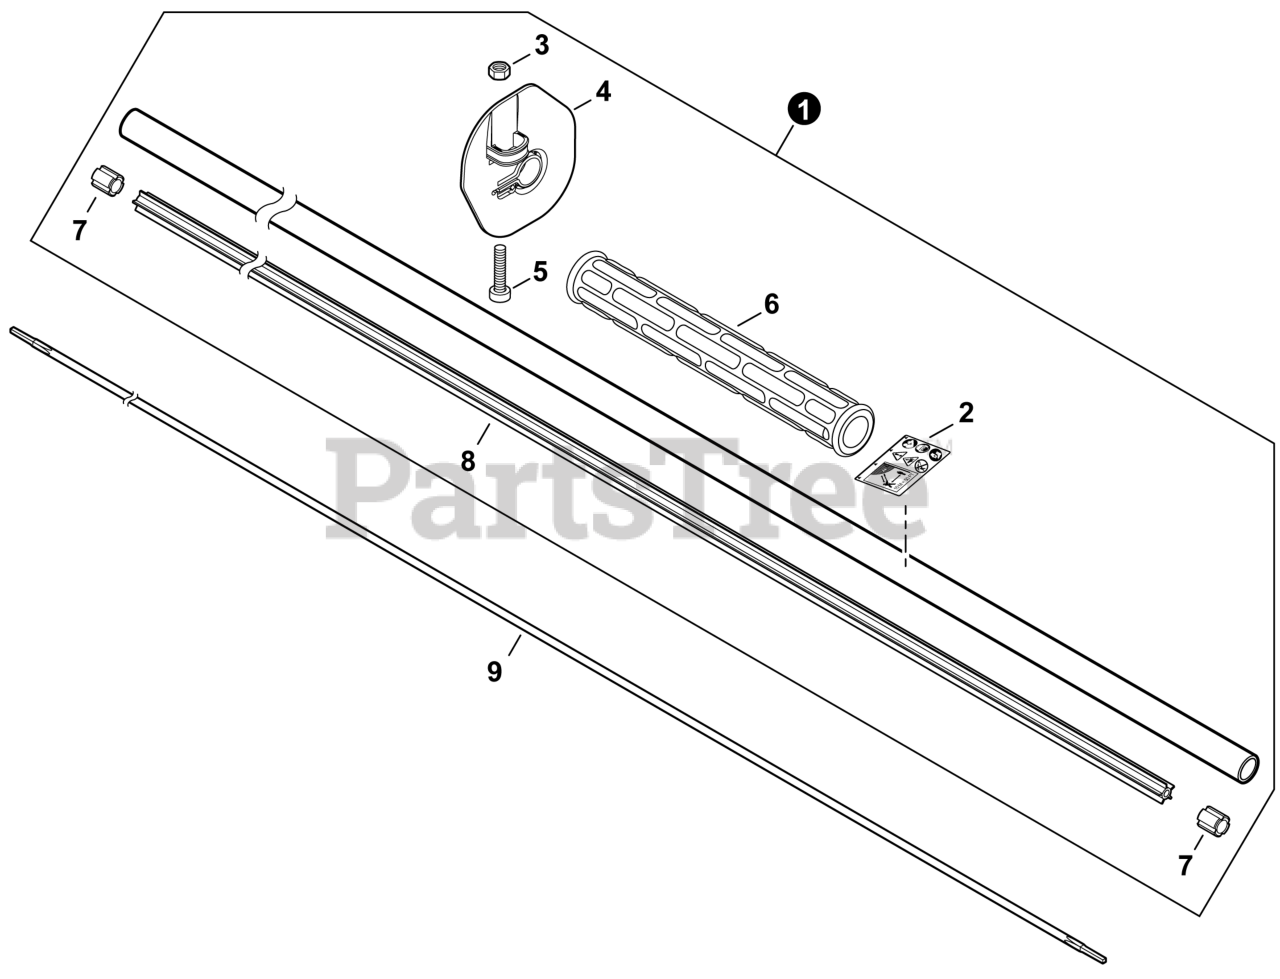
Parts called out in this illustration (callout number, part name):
1	MAIN PIPE ASSY
2	LABEL - CAUTION ISO
3	NUT M5
4	GUARD, HAND
5	BOLT, TORX 5x20
6	GRIP, FRONT
7	STOPPER
8	LINER, FLEXIBLE
9	DRIVESHAFT - FLEXIBLE
